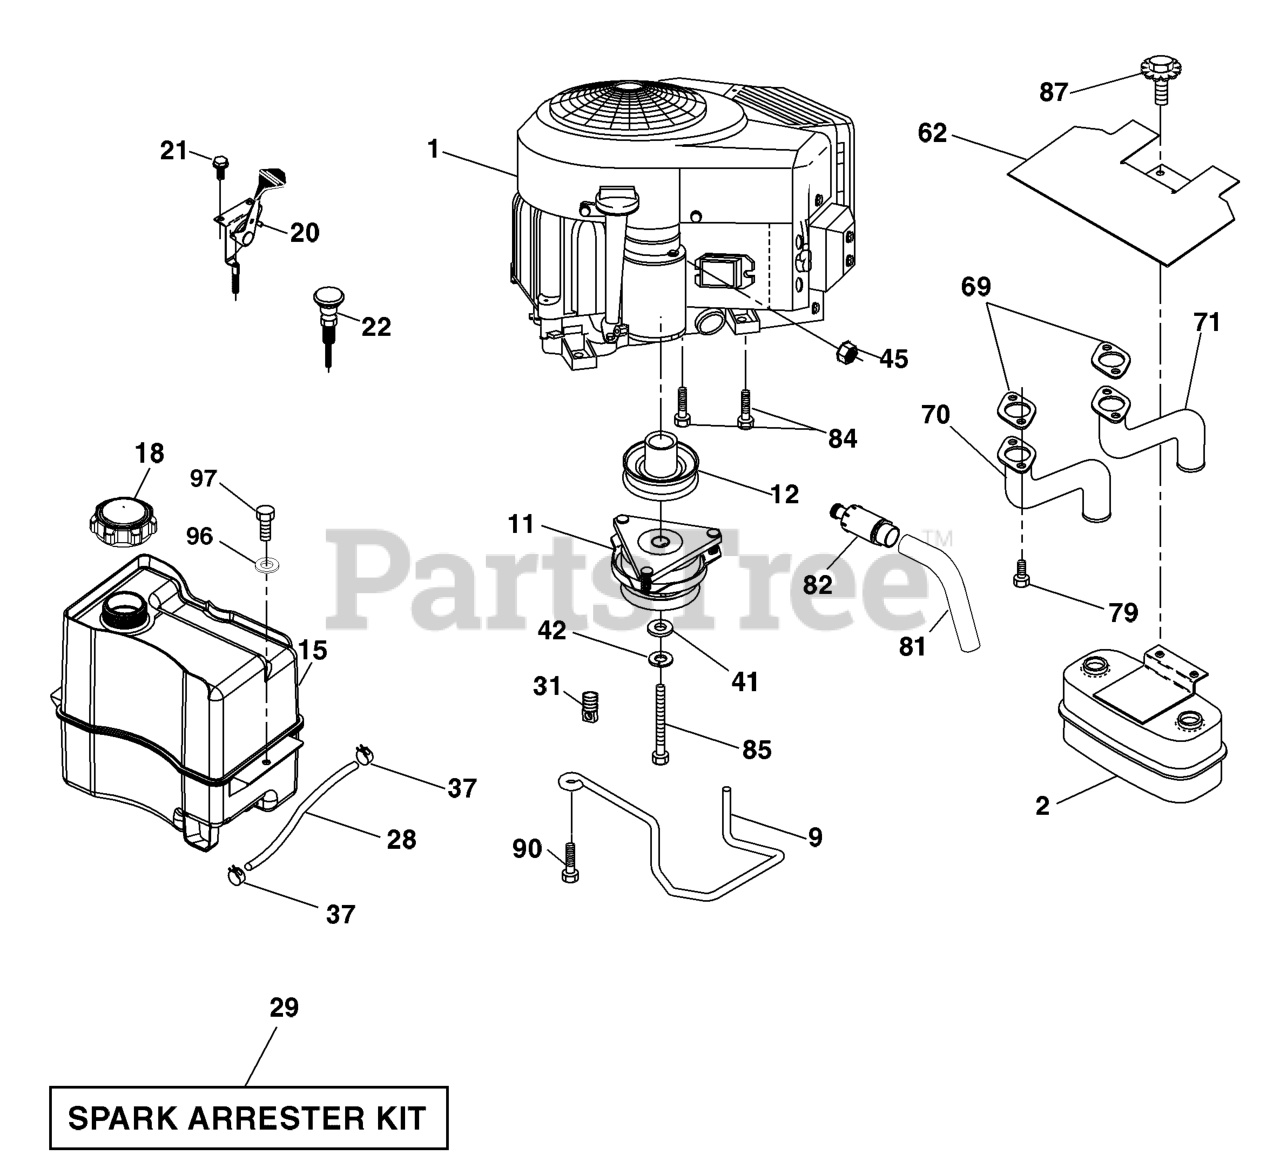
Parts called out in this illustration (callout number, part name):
2	MUFFLER.TWIN.CYL.LOW.TONE
9	KEEPER.BELT.ENGINE.4.2
11	CLUTCH.ELECTRIC.LT.48"*
12	PULLEY.ENGINE.TUFFTORQ
15	TANK.ASM.FUEL.FR.2.5GA.
18	FUEL CAP
20	THROTTLE CABLE
21	SCREW.#10 X 0.750.BOS THREAD
22	Choke Control
28	LINE.FUEL.20"FRONT.EMI
29	KIT.SPARK ARRESTOR 794945 B&S
37	HOSE CLAMP
42	LOCKWASHER
45	NUT
62	RP SHIELD HEAT MUFFLER
69	GASKET.MUFFLER
70	RP.EXHAUST.TUBE.LH.BS/TWIN
71	EXHAUST.TUBE.RH.BS/TWIN
79	SCREW.SOCKET.HEAD.5/16-18
81	TUBE, DRAIN OIL ASM.
82	PLUG DRAIN OIL EASY
84	SCREW.3/8-16
85	BOLT HEX 7/16-20X4-1/4"
86	NUT.HEX.FLANGE.TOPLOCK
87	BOLT 5/1618UNC X 3/4 W/ SEMS
90	SCREW 3/8-16X1
96	WASHER
97	SCREW HEXWSHR 1/4-20X3/4
